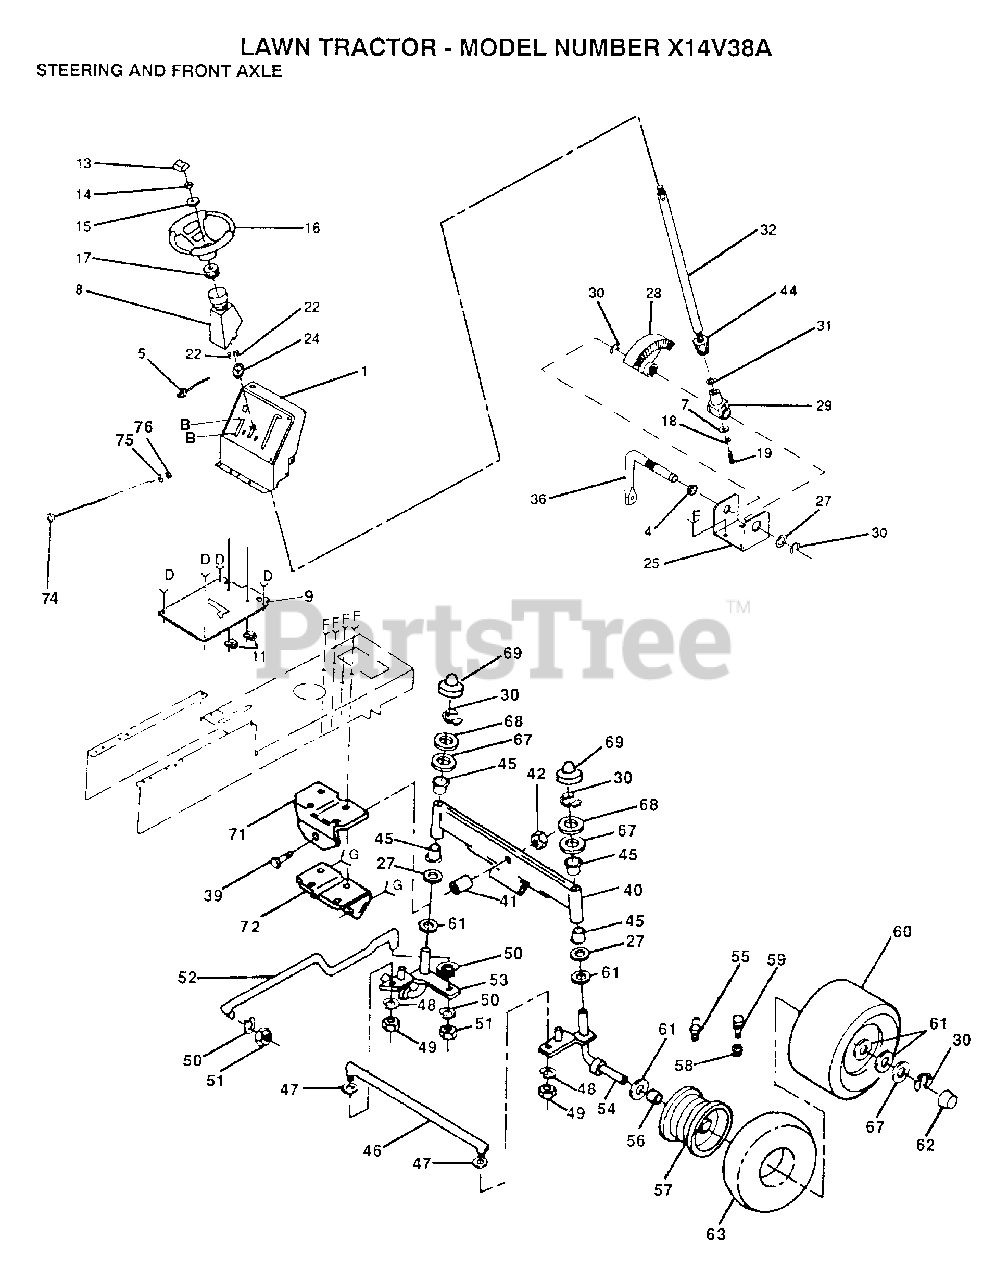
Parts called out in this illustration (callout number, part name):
4	NYLINER T
8	BOOT STR SHAFT
11	CLIP T
13	INSERT-WHEEL LT
15	WASHER
17	ADAPTER LT
18	LOCKWASHER
19	"SCREW,SPECIAL"
24	"BUSHING,STEERING"
25	"BRKT,STEERING"
27	WASHER .T
29	SUPPORT.SHAFT
30	RING
31	THRUST WASHER
39	BOLT LT
40	FRONT AXLE
41	BEARING
42	"NUT-LOC,FLANGE LT"
44	"GEAR,PINION"
45	COL. SRTG. BEAR.
46	ROD TIE
47	WASHER M
48	LOCKWASHER
49	NUT.LOCK.5/16-24
50	LOCKWASHER
53	SPINDLE-LH LT
55	FITTING LT
56	"FLANGE, BEARING"
58	VALVE CAP
59	VALVE STEM LT
61	WASHER
62	HUB CAP
63	TUBE.5.3/4.5/6
67	WASHER
68	WASHER
69	CAP
71	SUPPORT-SADDL T
72	SUPPORT.SADDLE.FT
75	LOCKWASHER
